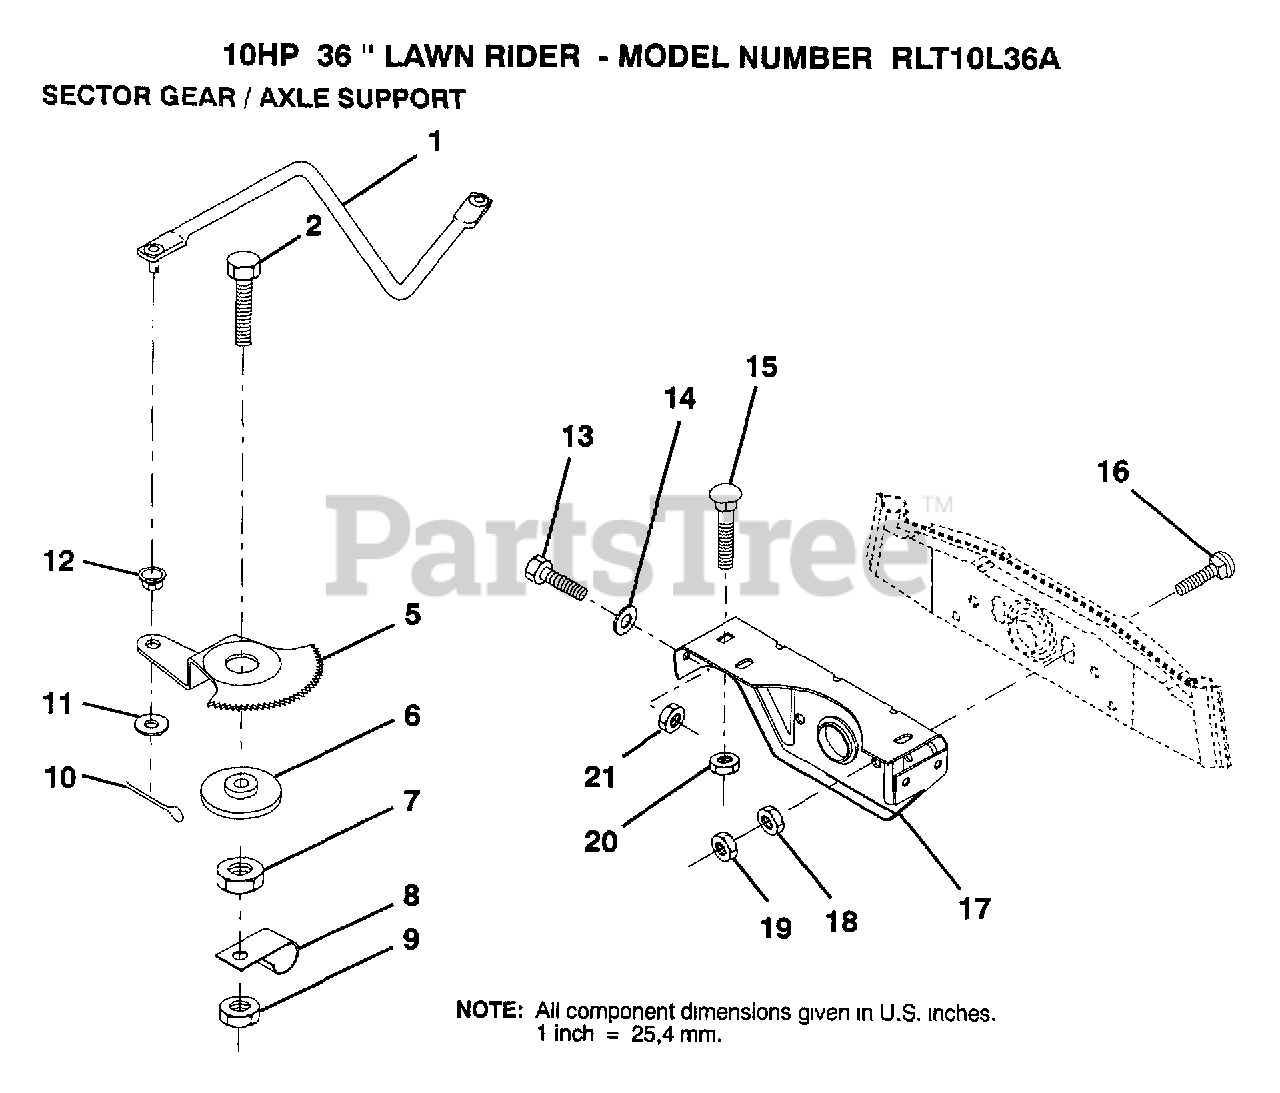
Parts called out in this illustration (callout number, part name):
1	DRAG LINK
2	"BOLT,HEX"
5	GEAR SECTOR
6	BUSHING
7	NUT
8	CLIP INSULATOR
9	NUT LTV
10	COTTER PIN
11	WASHER
12	BUSHING.DRAGLINK
13	BOLT
14	WASHER
15	BOLT
16	BOLT
17	"SUPT,FRT AXLE"
18	NUT.HEX.3/8-16UNC
19	LOCKNUT
